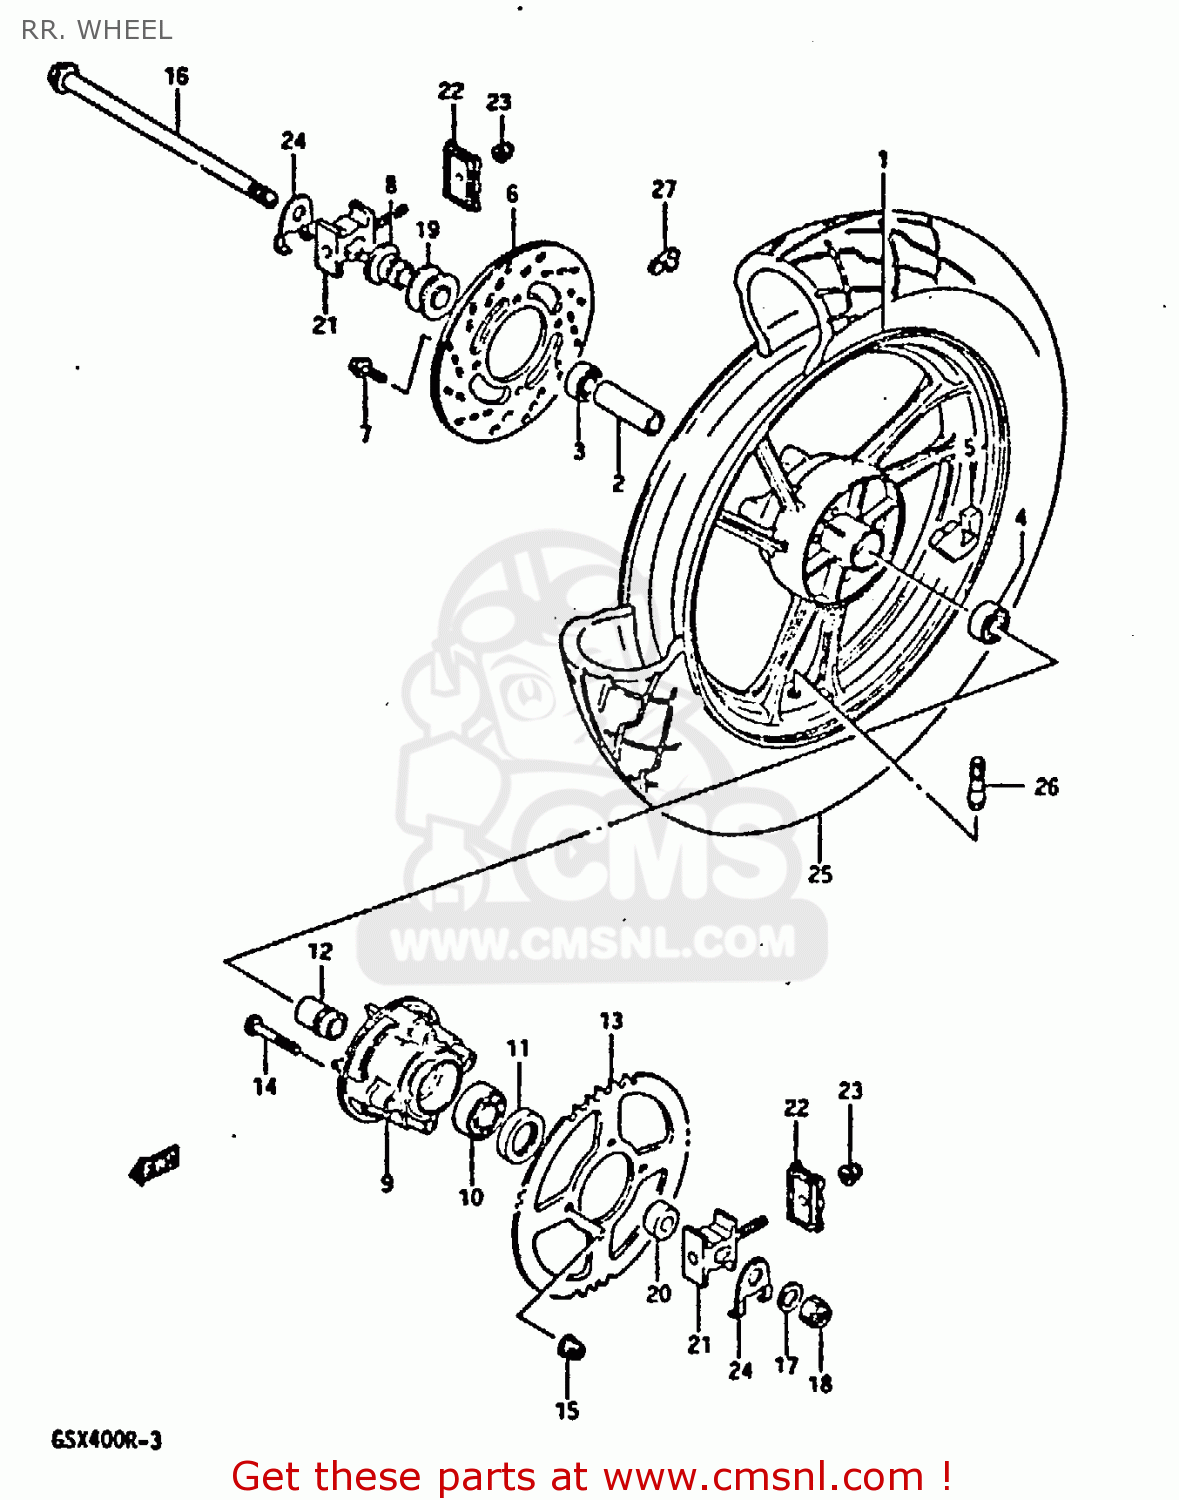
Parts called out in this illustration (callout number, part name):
1	WHEEL,REAR
2	SPACER(17.5X25X81)
3	BEARING
4	BEARING
5	ABSORBER,RR HUB SHOCK
6	DISC,REAR BRAKE (BLACK)
7	BOLT
9	RR SPROCKET DRU
10	BEARING
11	SEAL,OIL(34X54X8)
12	RETAINER,RR SPROCKET DRUM
13	SPROCKET,RR(46T)
14	BOLT
15	NUT
17	WASHER (17X30X3.2)
18	NUT 16MM
20	SPACER(17X34X16.5)
21	CHAIN ADJUSTER
22	PLAAT.SPANNER
23	NUT
24	WASHER,CHAIN ADJUSTER
25	TIRE,RR
26	VALVE,TIRE
27	BALANCER,WHEEL
